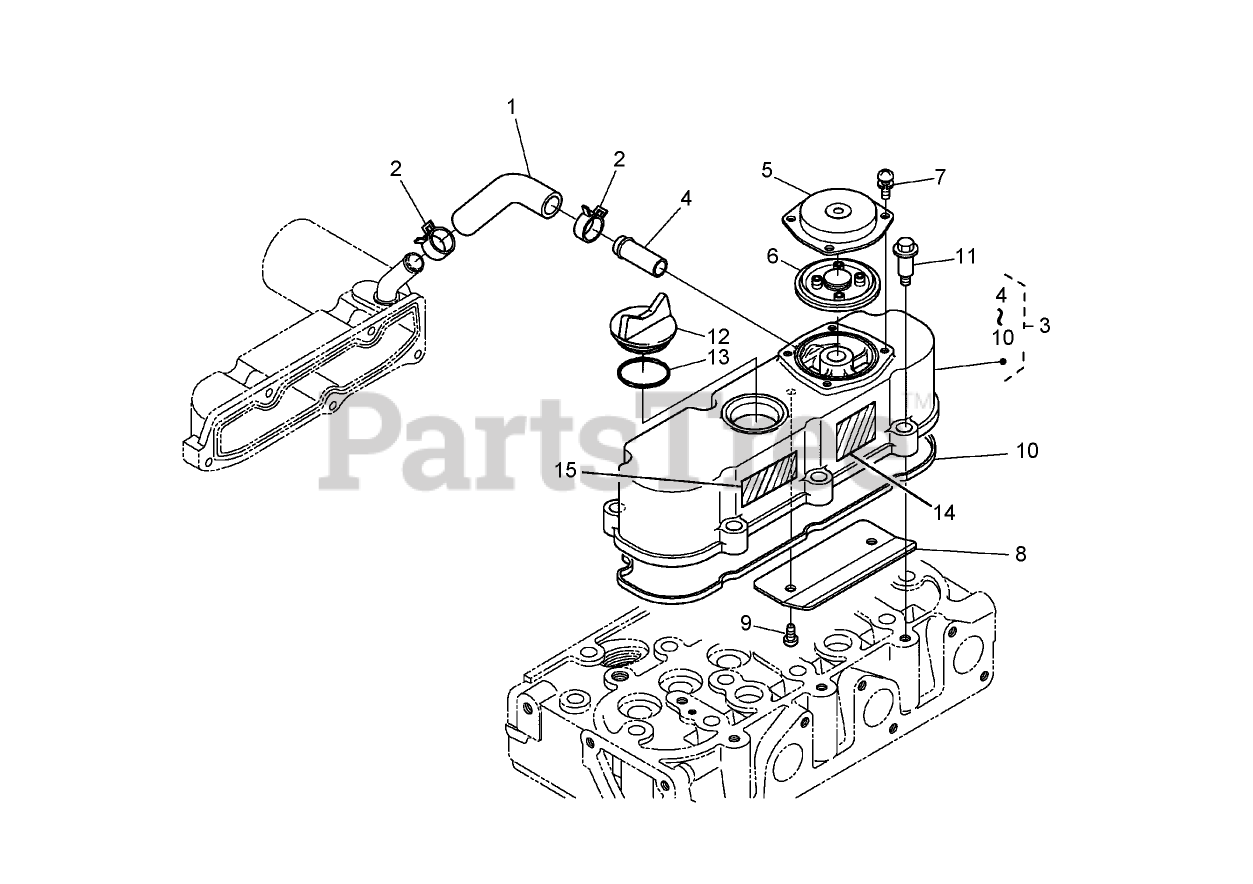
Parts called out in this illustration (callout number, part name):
1	TUBE-BREATHER
2	CLAMP-HOSE
3	CYLINDER HEAD COVER ASM
4	PIPE-RETURN, WATER
5	COVER-BREATHER
6	VALVE-BREATHER
7	SCREW (WITH WASHER)
8	SHIELD-BREATHER
10	GASKET-COVER, HEAD
12	PLUG-FILLER, OIL
13	O-RING
14	DECAL-CAUTION
15	LABEL-INSTRUCTION
